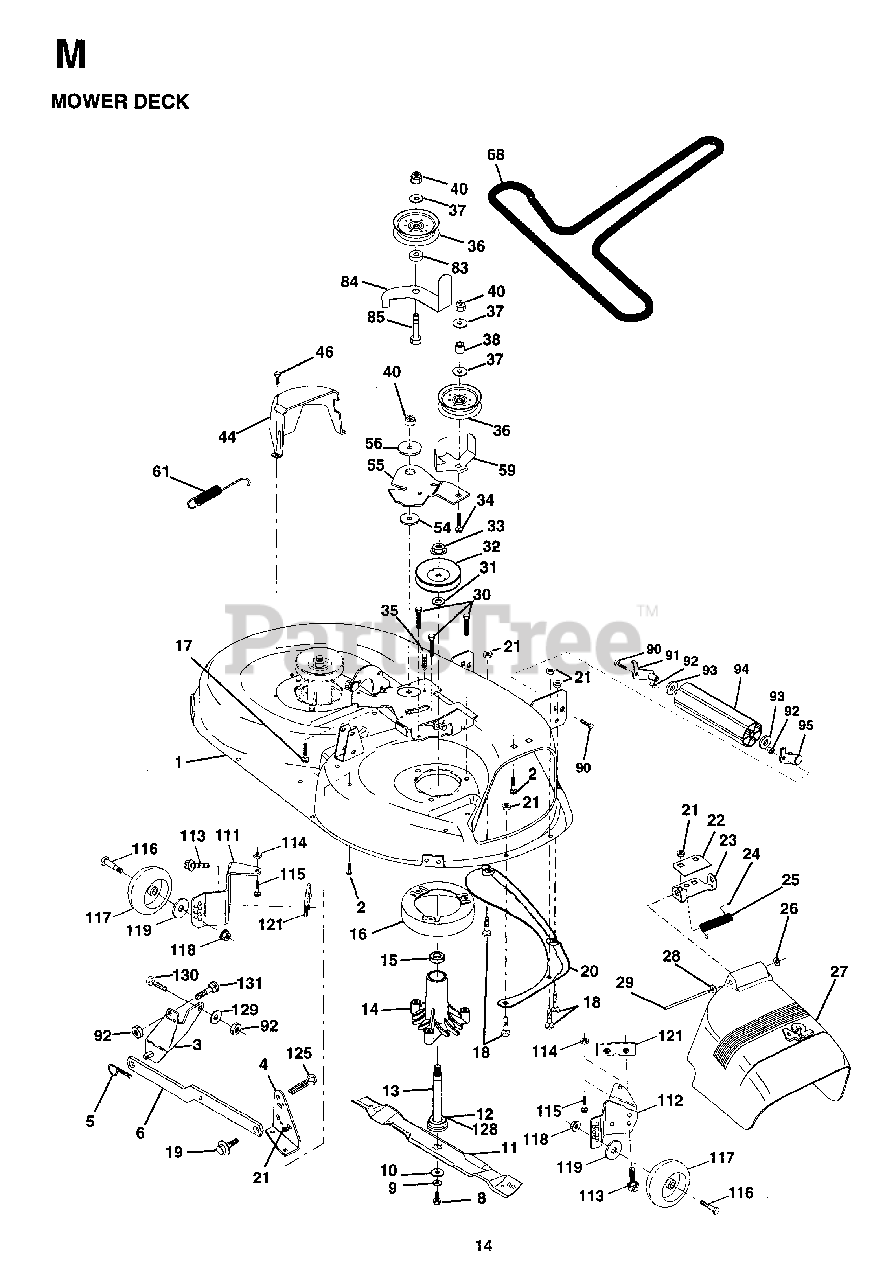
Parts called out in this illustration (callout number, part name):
1	DECK 42"
2	BOLT
3	BRKT ASM SWAY BAR
4	BRKT DECK SW BAR
5	RETAINER-SPRNG RB
6	REAR SUSP ARM
8	BLADE BOLT
9	LOCKWASHER
10	WASHER.BLADE
12	BEARING
13	SHAFT ASM VENT
14	HSG MANDREL
16	STRIPPER
17	BOLT CARRIAGE
18	BOLT
19	BOLT SHD 5/16-18
20	BAFFLE
21	LOCKNUT
22	STIFFENER BRACKET
23	DEFLECTOR BRACKET
24	CAP-SLEEVE LT
25	SPRING TORSION
26	NUT PUSH M
27	SHIELD.DEFLECTOR.MOWER.42".BLK
28	WASHER
29	ROD.HINGE
30	SCREW
31	WASHER
32	PULLEY/MANDREL
33	NUT
35	FASTENER.XMAS.TREE
36	FLAT IDLER PULLEY
38	IDLER SPRING SPACER
40	LOCKNUT
44	GUARD MANDREL LH BLACK
46	SCREW.1/4-20X5/8
54	HARDENED WASHER
55	IDLER ARM
56	SPACER RETAINER
59	GUARD, BELT
61	SPRING EXTENSION
84	KEEPER.BELT.IDLER
85	BOLT
90	BOLT
91	BRACKET LH (A)
92	LOCKNUT
94	NOSE ROLLER
95	BRACKET RH (B)
111	BRACKET WHEEL GAUGE LH 42" DK
112	BRACKET WHEEL GAUGE RH 42" DK
113	SCREW
114	NUT
115	BOLT
118	LOCKNUT
119	WASHER
121	BRACKET.EXTRD.GWL
125	COTTER PIN
128	WASHER FELT
129	WASHER
131	BOLT D
